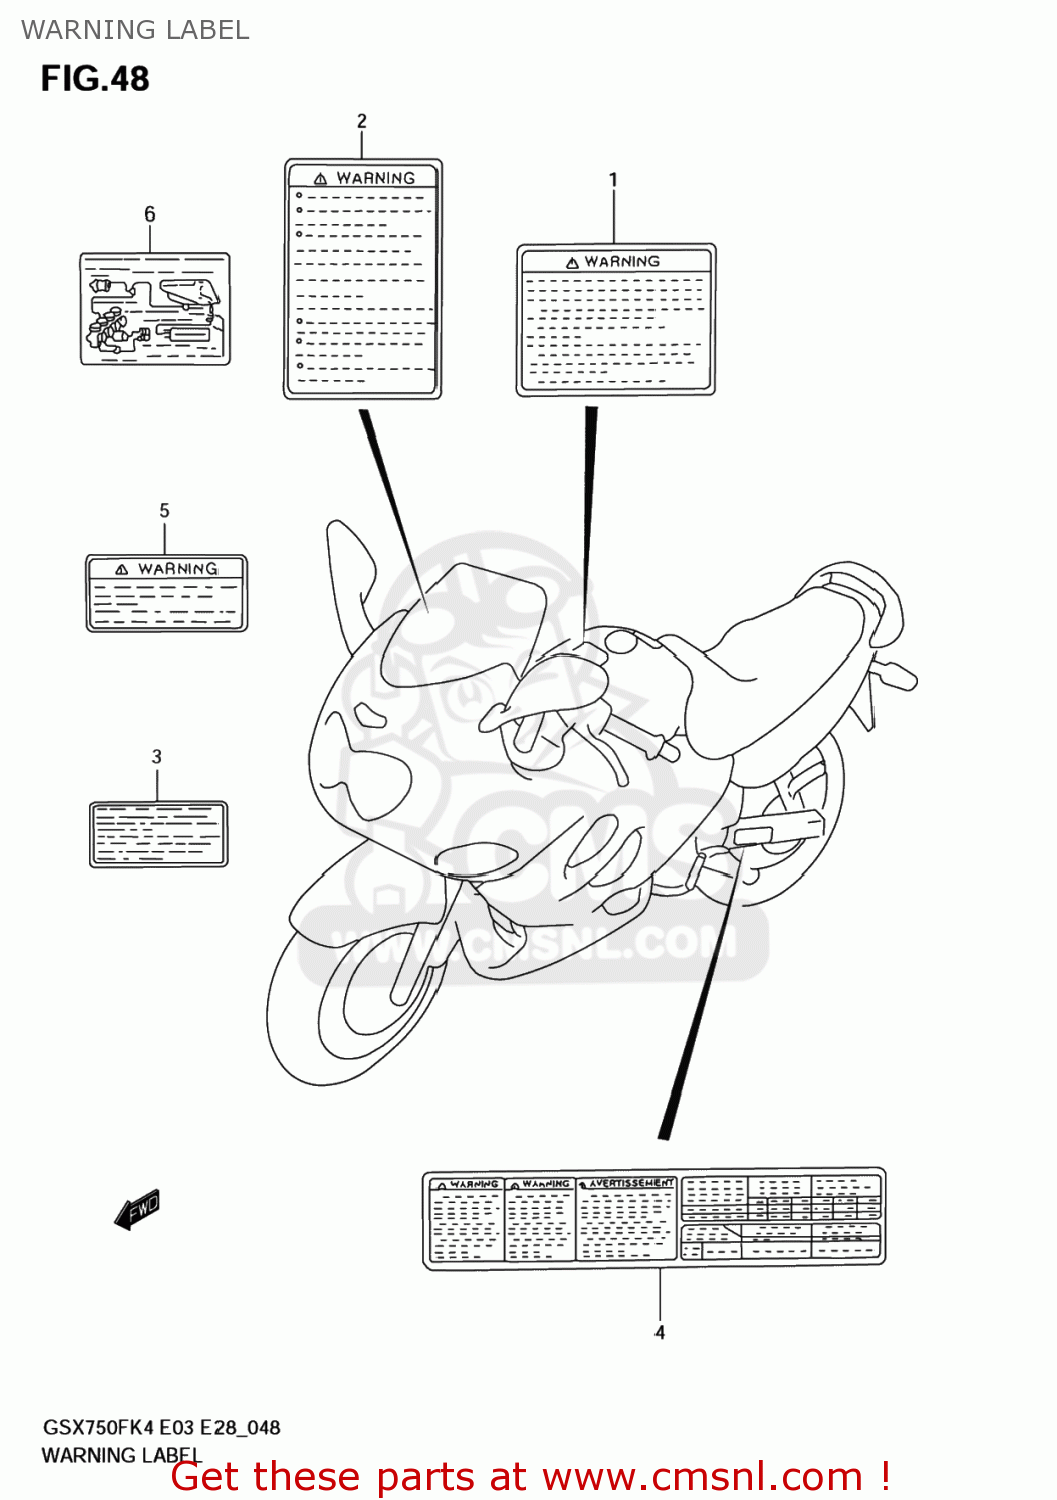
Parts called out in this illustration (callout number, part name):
1	LABEL,GENERAL WARNING
2	LABEL,SCREEN
3	LABEL,MANUAL NOTICE
4	LABEL,TIRE INFORMATION
5	LABEL,WARNING STEERING
6	LABEL,VACUUM HOSE ROUTING
7	MANUAL,OWNER'S
